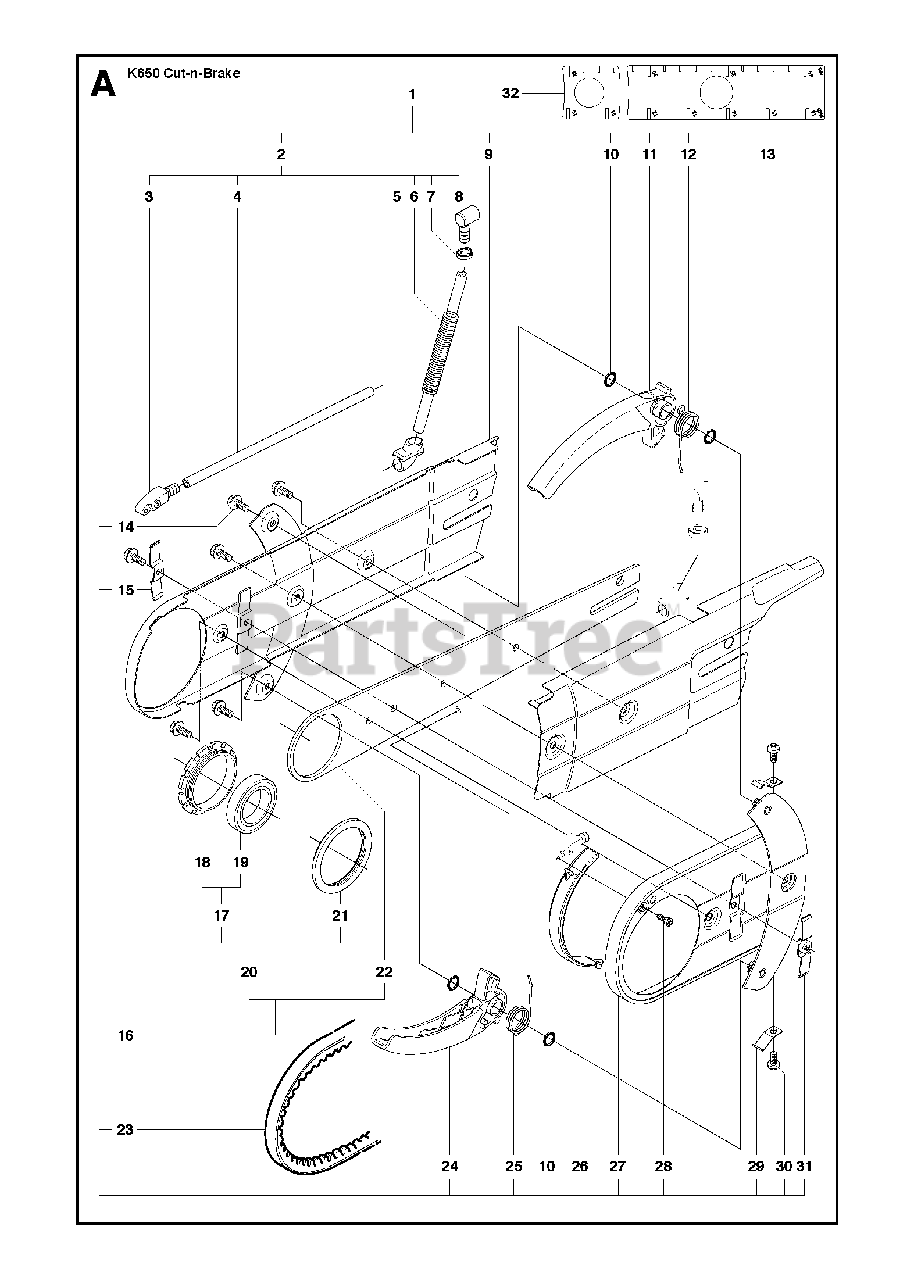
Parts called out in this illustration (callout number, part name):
1	CUTTER ARMIncl. 2, 9 - 16, 23 - 31
2	HOSEIncl. 3 - 7
4	HOSE
6	PROTECTIVE SPRING
9	BELT GUARD
14	SCREW EHHFM
15	DEFLECTION LIMITER
16	BARIncl. 20, 22
17	BEARING CAGEIncl. 18, 19
18	BEARING CAGE
28	SCREW CCRPANT
30	SCREW CRPANM
31	DEFLECTION LIMITER
